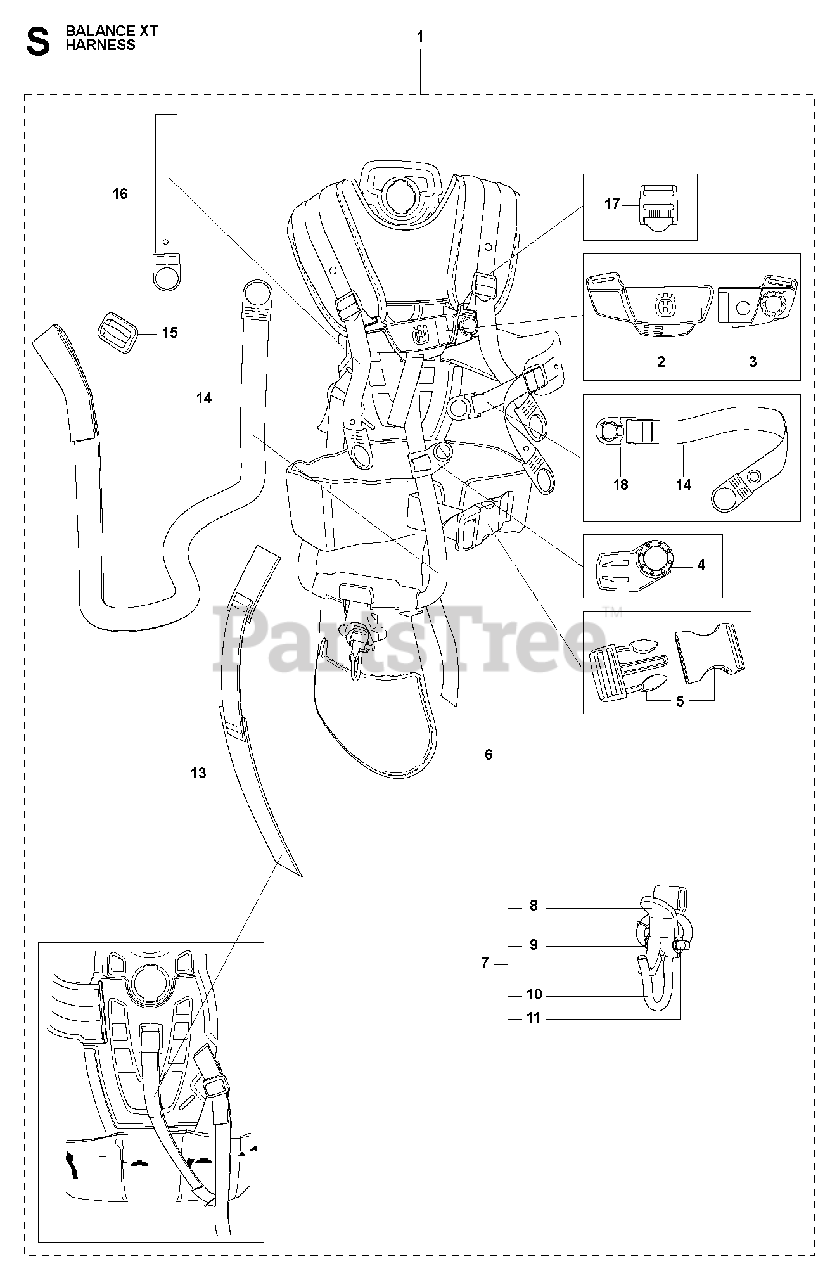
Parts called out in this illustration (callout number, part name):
1	HARNESS BALANCE XT
2	FRONT PIECE
3	FRONT PIECE
4	SNAP LOCKING
5	BUCKLE
6	HIP BAND
7	WELT HOOK
8	CATCH *
9	SPRING LOCKING
10	HOOK
11	E-RING 5
13	BAND
14	BAND
15	RP CLIP
16	BAND
17	BUCKLE
18	SNAP LOCKING
